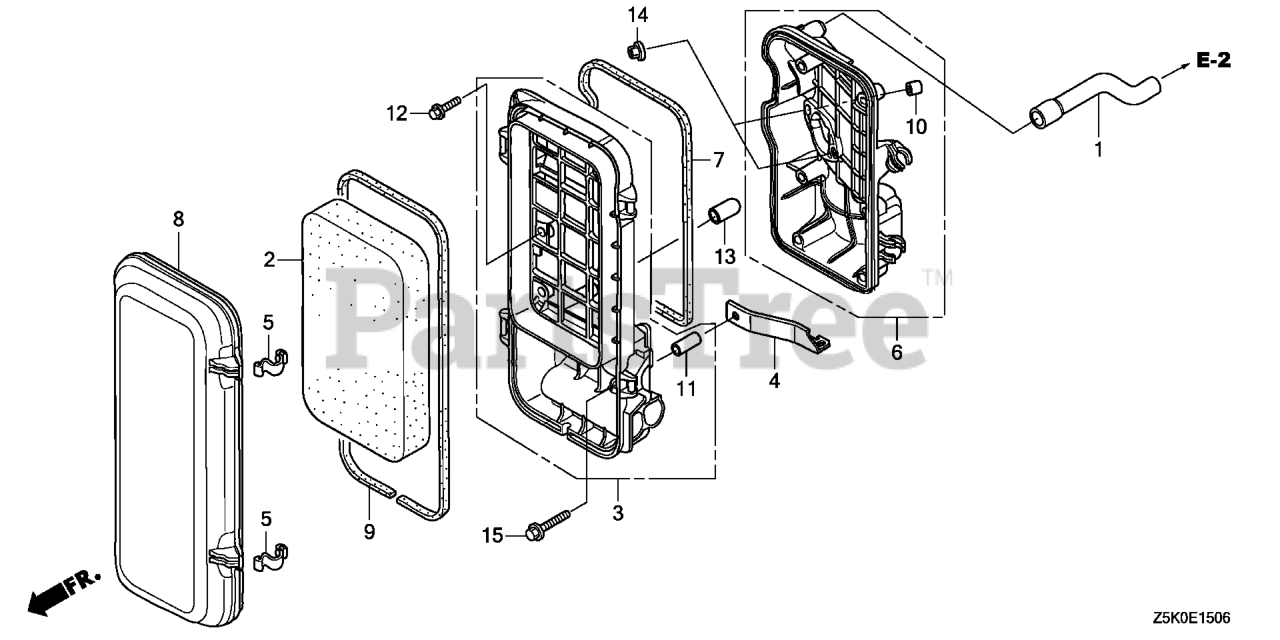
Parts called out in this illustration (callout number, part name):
1	TUBE, BREATHER
2	ELEMENT, AIR CLEANER
3	HOUSING, AIR CLEANER
4	STAY, AIR CLEANER
5	SPRING, AIR CLEANER HOUSING LID
6	BASE, AIR CLEANER
7	SEAL, AIR CLEANER HOUSING
8	COVER, AIR CLEANER
9	SEAL, AIR CLEANER COVER
10	COLLAR, AIR CLEANER
11	COLLAR, AIR CLEANER
12	BOLT, FLANGE (5X18)
13	CAP, SEALING
14	NUT, FLANGE (6MM)
15	BOLT, FLANGE (6X32)
